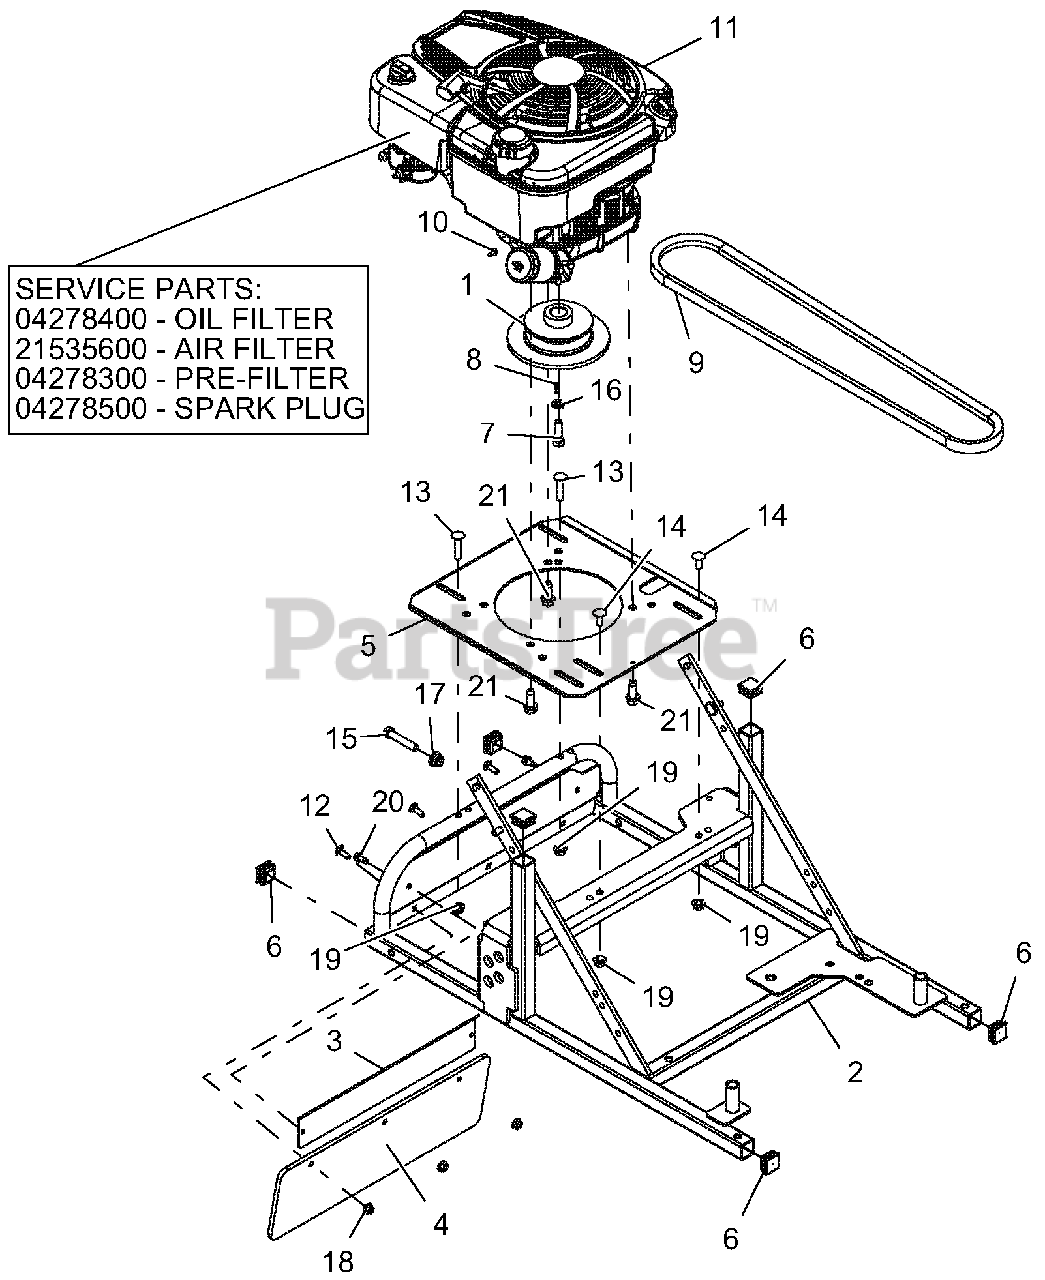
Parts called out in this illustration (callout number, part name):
1	SHEAVE, ENGINE, HW MOWER
2	WMT-HWM FRAME PLAIN
3	BACKER, GRAVELY
4	GUARD, RUBBER DEBRIS
5	PLATE-ENGINE MTG
6	CAP PLUG FOR 1" TUBE 14GA
7	BLT-HEX .38-24X1.25 GR8 YWZC
8	KEY-WDRF .156X.625X.25 SAE 6
9	V-BELT, HB-WRAPPED
10	SCR-TAP 8-32X.38 SL HWH YWZC
11	ENGINE, B&S 190PRO 8.5 GT CARB
11	FILTER, OIL
11	FILTER, AIR
11	AIR FILTER, PRE-CLEANER
11	SPARK PLUG
12	@BLT-RDHDSQNK .25-20X.75 G5YZ
13	@BLT-RDHDSQNK .31-18X1.50 G5YZ
14	@BLT-RHDSSQNK .31-18X.75 G5YZ
15	BLT-HEX .38-16X2.0 GR5 FTD YWZ
16	@WSHR-LK .38X.094 REG YWZC
17	@NUT-LK-NYL-FLG .38-16 YWZC
18	@NUT-LK-TOP-FLG .25-20 YWZC
19	@NUT-LK-TOP-FLG .31-18 YWZC
20	SCR-TAP .25-20X.50 HWH TR YWZ
21	@SCR-TAP .38-16X1.00 HWH TR YZ
